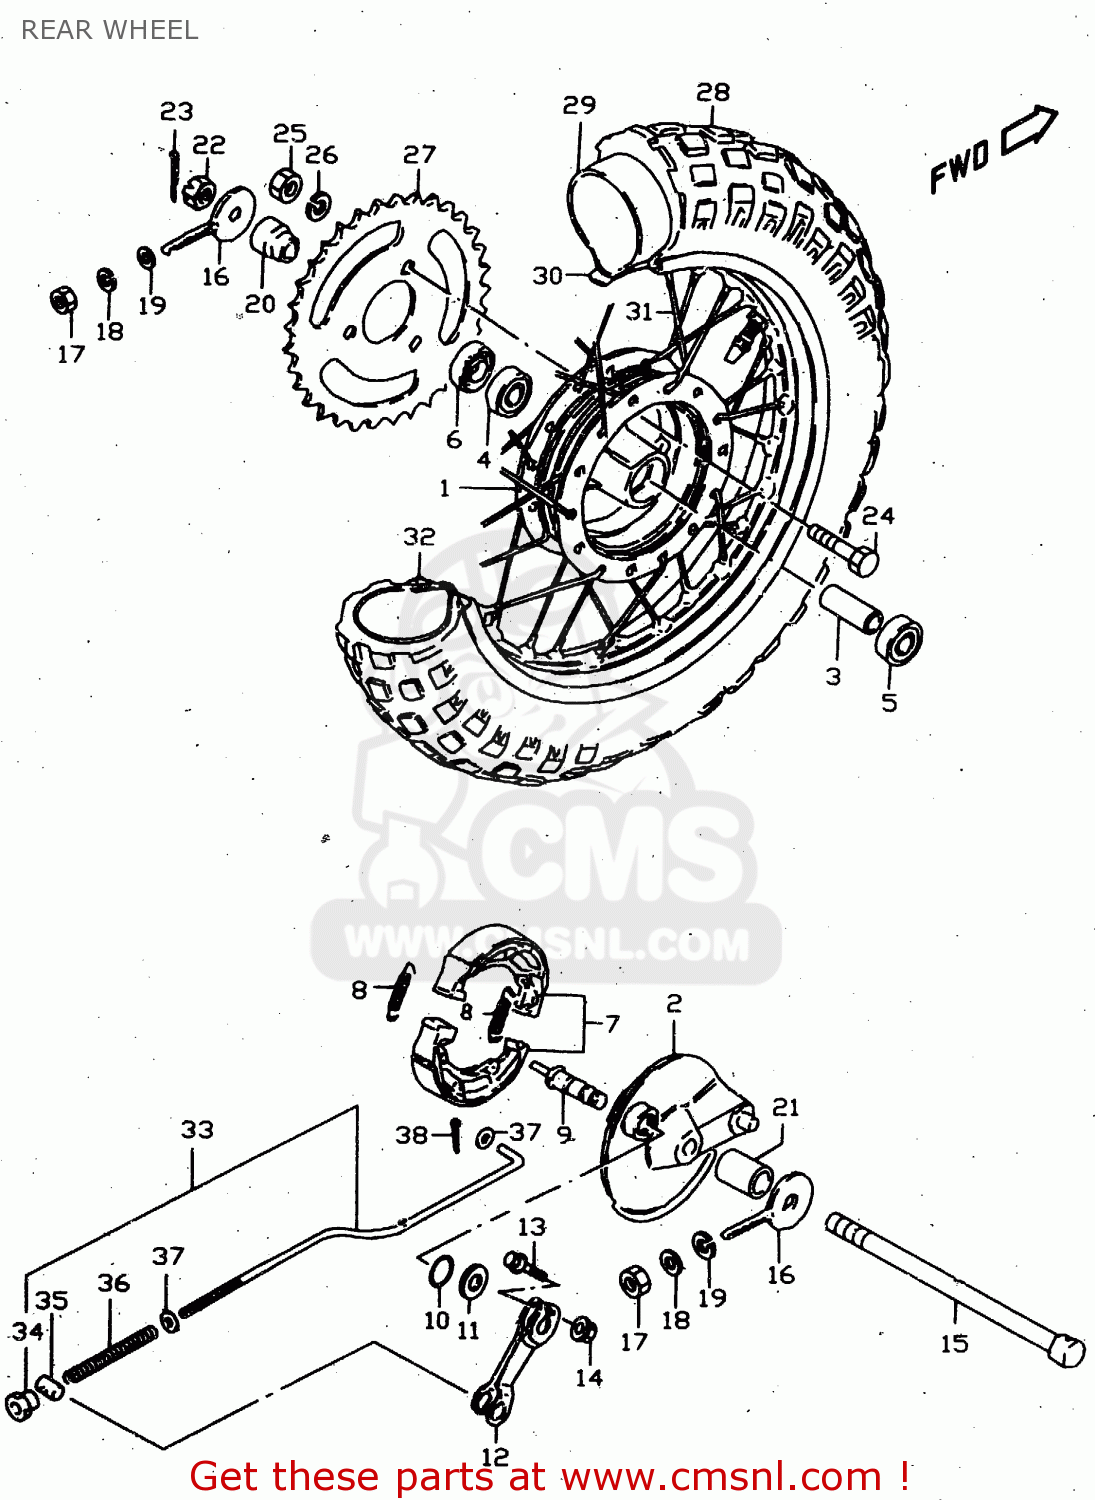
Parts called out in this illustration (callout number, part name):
1	HUB,RR WHEEL
2	PANEL,RR BRAKE ANCHOR
3	SPACER(10.2X16X55)
4	BEARING(10X26X8)
5	BEARING
6	SEAL,OIL(15X27X6)
7	SHOE & SPRING SET (NAS)
8	SPRING(L:35.8)
9	CAM,BRAKE
10	O RING(D:2.4,ID:9.6)
11	WASHER(10.5X18X1)
12	LEVER,RR BRAKE CAM
13	BOLT
14	NUT
15	AXLE,RR
16	ADJUSTER,CHAIN
17	NUT 6MM
18	LOCK WASHER
19	WASHER
20	SPACER,RR AXLE,L
21	SPACER,RR AXLE,R
22	NUT
23	PIN 20X20
24	BOLT(8X36)
25	NUT
26	WASHER,LOCK
27	SPROCKET,RR
28	TIRE
29	TUBE,INNER
30	PROTECTOR,INNER TUBE
31	SPOKE SET,RR
32	RIM,WHEEL
33	ROD ASSY,RR BRAKE
34	NUT
35	PIN,10X19
36	SPRING
37	WASHER
38	PIN
